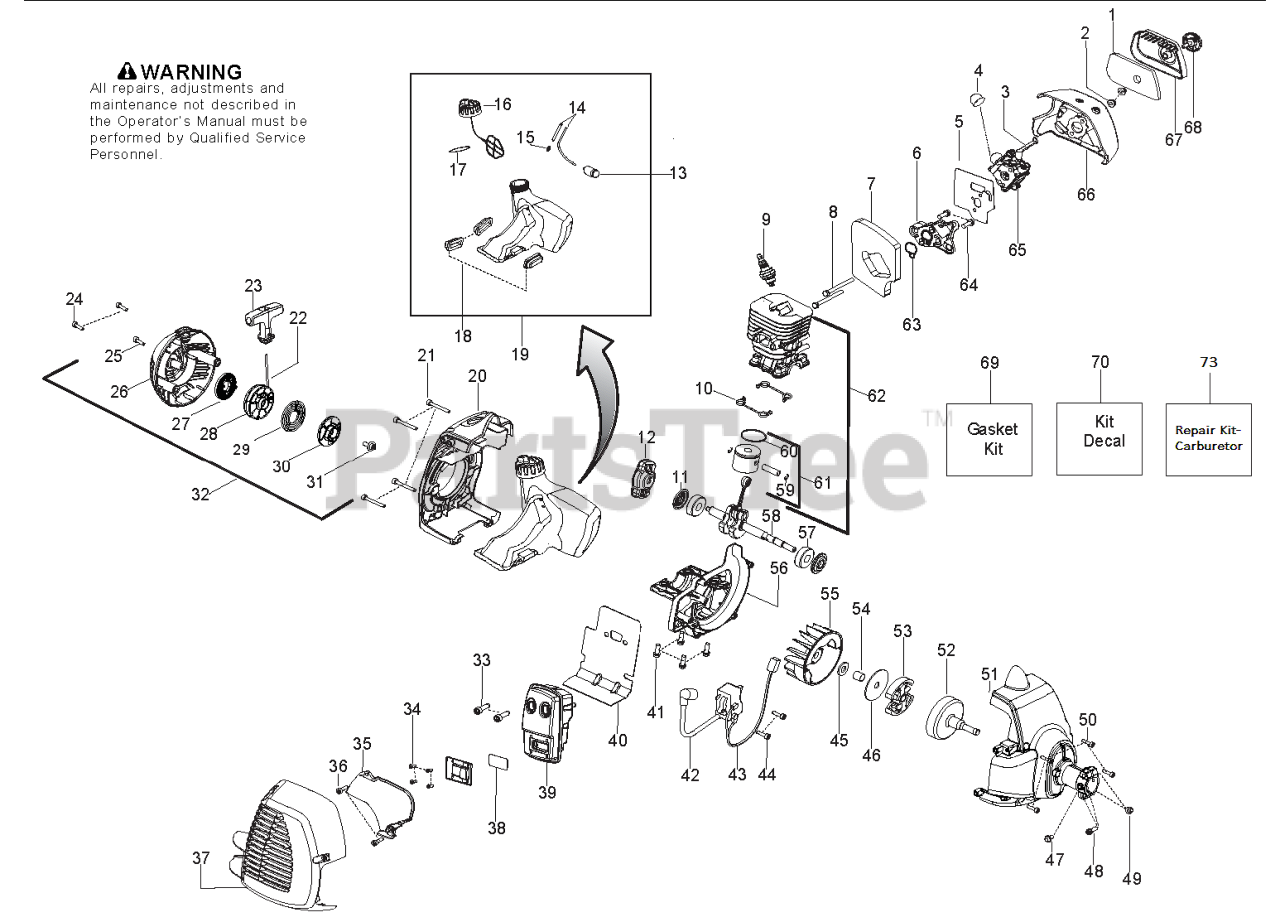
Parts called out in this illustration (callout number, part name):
1	FILTER AIRBOX
3	CHOKE LEVER
4	PURGE BULB ZAMA
5	KIT GASKET 28CC
6	CARB ADAPTOR
7	KIT GASKET 28CC
8	BOLT CARB ADAPTOR
9	BPMR6A NGK SPARK PLUG
10	KIT GASKET 28CC
11	KIT GASKET 28CC
12	STARTER PAWL BRIDGE
13	ASSY FUEL PICKUP PRE FLUSHED
14	KIT-LINE(FUEL)
15	FUEL LINE FITTING
16	FUEL CAP ASSY
17	KIT GASKET 28CC
18	ISOLATOR FUEL TANK
19	KIT FUEL TANK HVA
20	REAR SHROUD ORANGE
22	KIT ROPE
23	STARTER HANDLE
24	SCREW M5-0.8X30MM
25	SCREW M4 X 1.75 PT 16MM
26	HOUSING STARTER
27	KIT STARTER SPRING
28	KIT PULLEY/SPRING
29	DRIVER SPRING
30	PULLEY STARTER DRIVE
32	ASSY STARTER HSG HVA
33	BOLT MUFFLER
34	SCREW 6-19X.437
35	SHIELD HEAT
36	SCREW M4 X 1.75 PT 16MM
37	KIT MUFFLER GUARD HVA
38	KIT SPARK ARRESTOR SCREEN
39	KIT MUFFLER W/CATALYST
40	KIT GASKET 28CC
41	SCREW-M5-0.8 X 25MM(TAP)
42	IGNITION MODULE MBU-7
43	ASSY MODULE LEAD WIRE
44	SCREW M4 X .70 TT 16MM
45	WASHER CLUTCH
46	WASHER-CLUTCH
47	SCREW-10-14 X 1/2 PLASTITE
48	SCREW-10-24 X 1" (UNC)
49	LOCKNUT-HEX 10-24
50	SCREW M4 X .70 TT 16MM
51	ASSY FAN HOUSING HVA 1"
52	KIT DRUM CLUTCH ASSY
53	ASSEMBLY CLUTCH
54	SPACER FLYWHEEL
56	CRANKCASE CAST 128
57	BEARING RADIAL BALL (6201)
58	CRANKSHAFT
59	WRIST PIN RET.
60	RING PISTON
61	KIT - PISTON
62	KIT PISTON CYL
63	KIT GASKET 28CC
64	SCREW-M5-0.8 X 25MM(TAP)
66	AIRBOX HVA 128 HUSKY GRAY
67	COVER-AIR BOX
68	KNOB ASSY AIRBOX COVER
69	KIT GASKET 28CC
